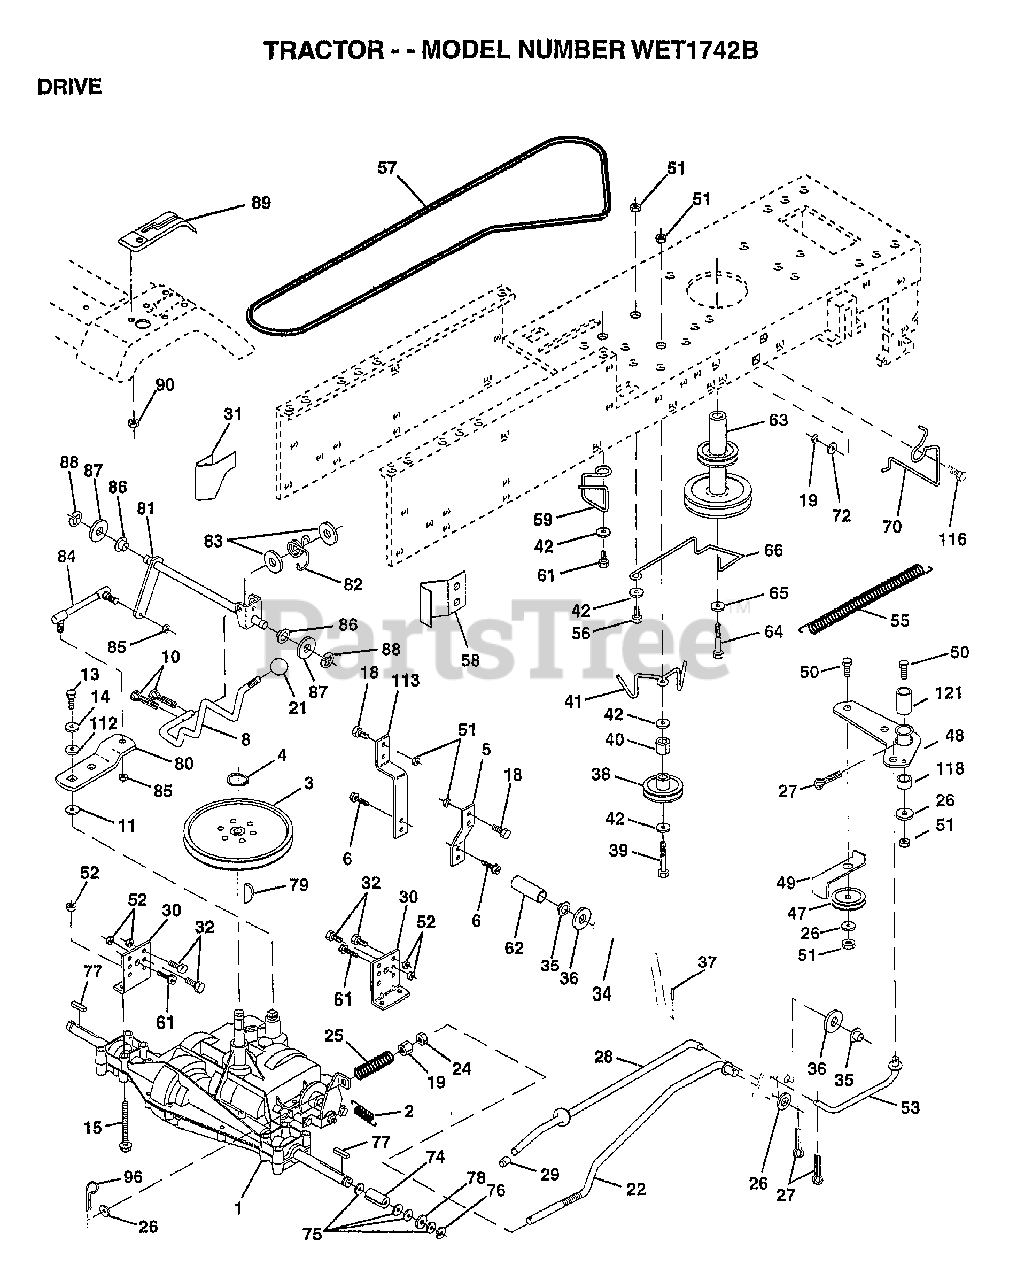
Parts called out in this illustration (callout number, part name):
1	TRANSAXLE PEERLESS
2	SPRING.BRAKE.RETU
3	PULLEY TRANS
5	SPRING
6	SCREW
8	ROD SHIFT FEND LT
10	PIN COTTER 1/8
11	WASH-SHFT PLT LT
13	BOLT.1/4-28.W/PAT
14	LOCKWASHER
15	BOLT.HX.FLG.5/16
18	BOLT
19	NUT
21	KNOB T (1/2-HOLE)
22	BRAKE ROD
24	NUT
25	SPRING ROD LT
26	WASHER
27	COTTER PIN
28	ROD.BRAKE.PARK.LT
29	PLUNGER CAP T
30	TRANSAXLE MTG BKT
31	"KEEPER,BELT LH T"
32	BOLT
34	SHAFT ASM-PEDAL F
35	NYLON BEARING
36	WASHER LT
38	PULLEY.IDLER.FLAT
39	BOLT
40	SPACER T
42	WASHER
48	BELLCRANK ASM
49	RETAIN BELT
52	NUT
53	"LINK, CLUTCH T"
55	"SPRING, RETURN LT"
58	"KEEPER,BELT RH T"
59	KEEPER BELT CNTSP
61	SCREW
62	PEDAL COVER T
63	PULLEY.ENGINE
64	BOLT
65	LOCKWASHER
66	KEEPER-BELT
70	KEEPER BELT ENG
72	WASHER
74	SPACER AXLE
75	WASHER
76	E-RING LT
77	SQUARE KEY
78	WASHER
80	"ARM.SHIFT.20""TIRE"
81	SHAFT.CROS.P930.
82	"SPRING,TORSION"
83	WASHER
84	"ROD.TIE.20""P930LT"
85	NUT.CNT.LOCK.1/4
86	BUSHING
87	WASHER D
88	KLIP RING
90	NUT
96	RETAINER M
112	WASHER LT
113	"STRAP,TORQUE"
116	BOLT RDHD 3/8-16
118	SPACER-BELLCRANK
121	NYLINER-CLUTCHING
